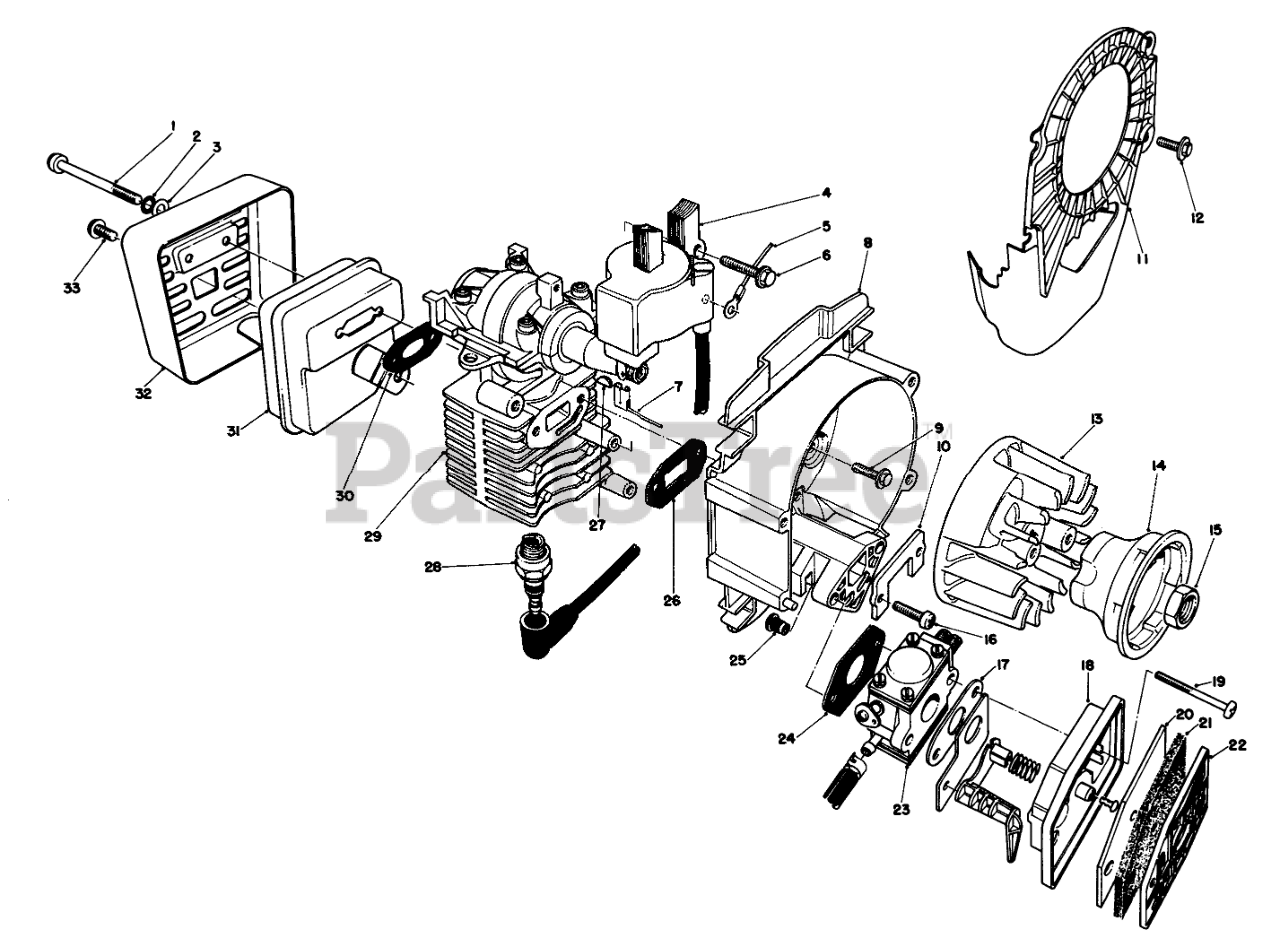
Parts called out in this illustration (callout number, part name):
1	MUFFLER SCREW
2	LOCKWASHER
3	Washer-Plain
4	BIM Module
5	Wire-Ground/Switch
6	Screw CDI
7	Wire-Coil/Switch
8	Backing Plate Assembly (Incl. Ref. #25)
9	Screw
10	Plate-Stress
11	Cooling Shroud
12	Screw-Shroud
13	Flywheel
14	Cup-Starter
15	NUT-JAM
16	Screw lntake
17	CHOKE GASKET
18	Choke & Spitback Cup Assy.
19	Screw-Carburetor
20	FILTER FELT
21	FILTER FOAM
22	FILTER COVER
23	CARBURETOR
24	CARB. GASKET
25	THREADED INSERT
26	INTAKE GASKET
27	FLYWHEEL KEY
28	SPARK PLUG (NGK)
29	SHORT BLOCK ASM
30	EXHAUST GASKET
31	Muffler Assembly
32	MUFFLER SHIELD WA
33	Screw, Muffler Tab
